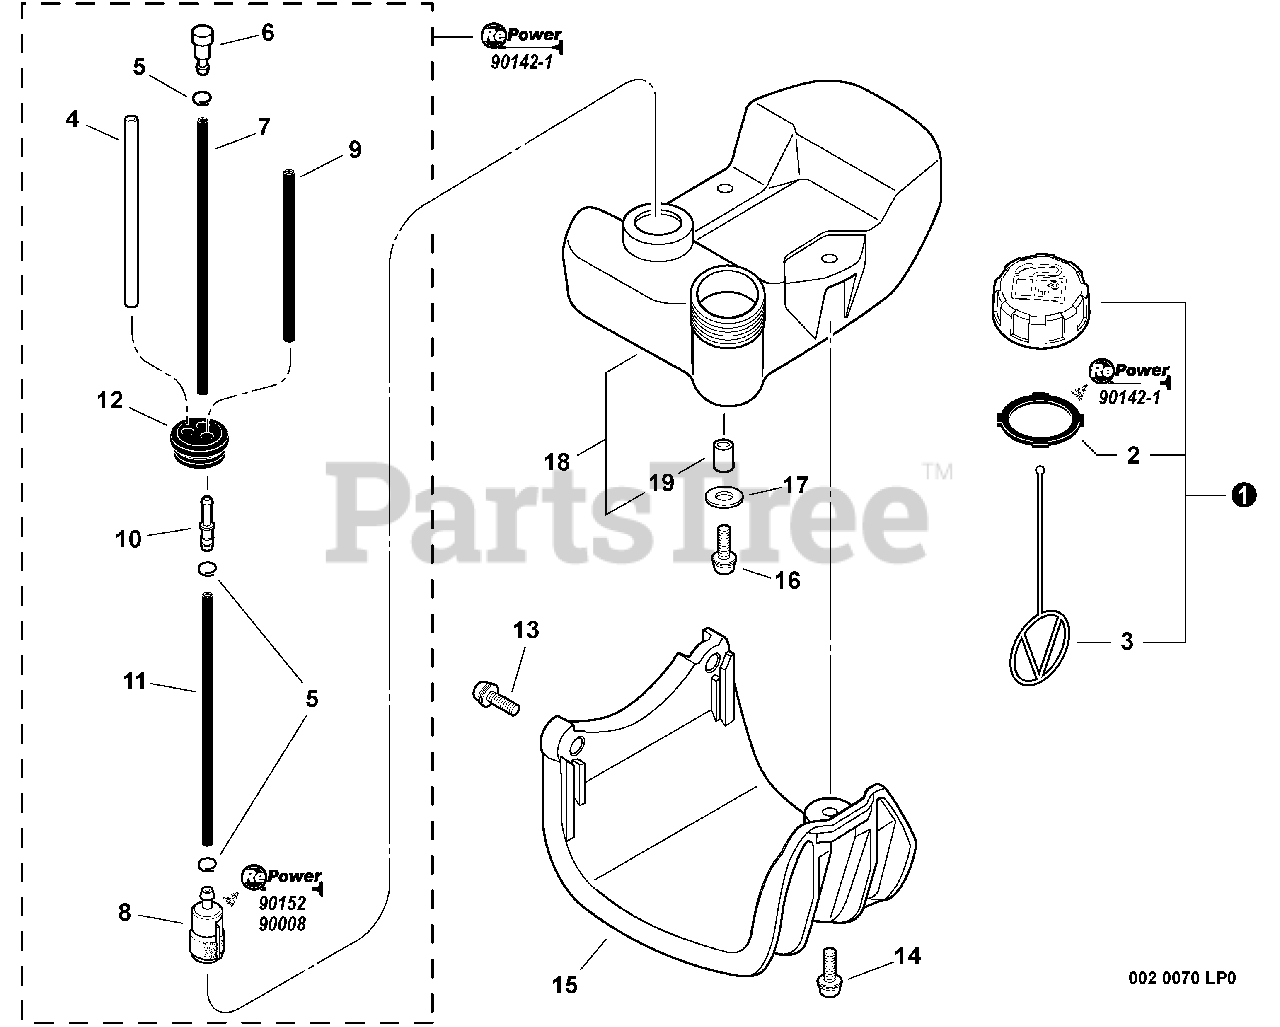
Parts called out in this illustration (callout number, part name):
1	CAP ASSY - ORANGE
2	GASKET, CAP
3	CONNECTOR, CAP
4	PIPE - 3X6X80 -- CLEAR
5	CLIP - 6.5
6	VENT, FUEL TANK
7	PIPE - 3X6X115 -- BLACK
8	FILTER, FUEL
9	PIPE - 3X5X74 -- BLACK
10	CONNECTOR, PIPE
11	PIPE - 3X6X100 -- BLACK
12	GROMMET
13	SCREW - 5X22
14	SCREW - 5X20
15	GUARD, FUEL TANK
16	SCREW - 5X16
17	WASHER - 5
18	FUEL TANK ASSY
20	RePower FUEL SYSTEM KIT
21	RePower TUNE-UP KIT
22	RePower FILTER KIT
